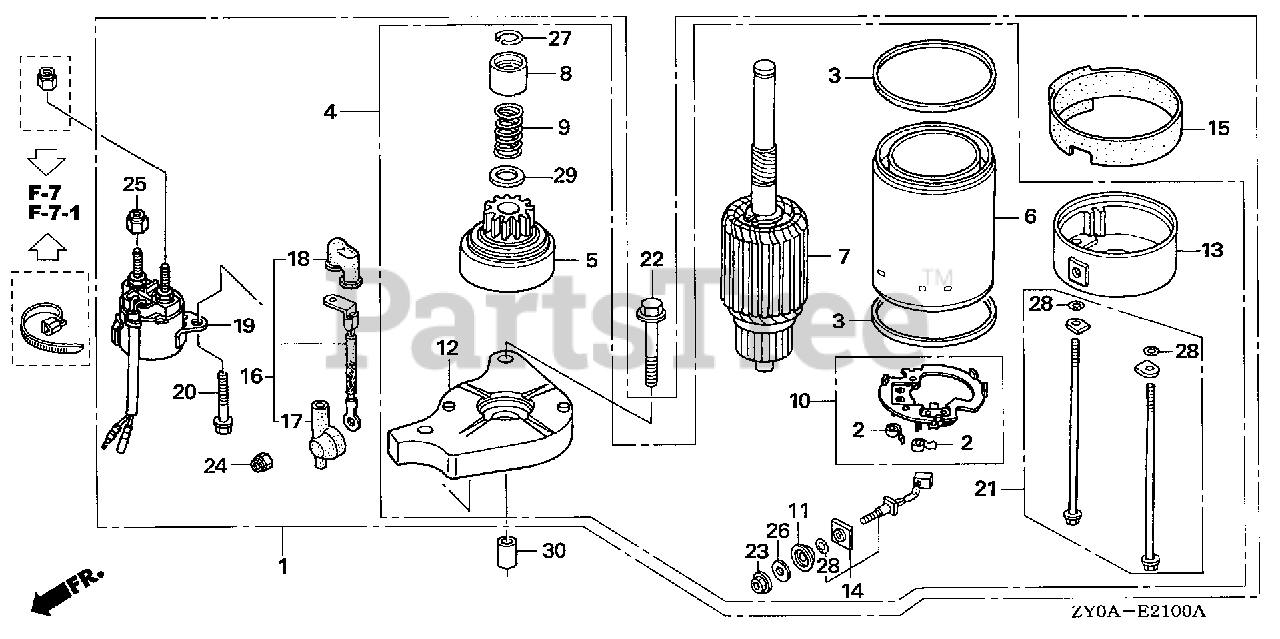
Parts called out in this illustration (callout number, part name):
1	STARTER MOTOR ASSY.
2	SPRING, CARBON BRUSH
4	STARTER MOTOR UNIT
8	PIECE, STOPPER
9	SPRING, RETURN
10	HOLDER, BRUSH
12	BRACKET, FR.
13	BRACKET, RR.
14	TERMINAL UNIT
15	SUSPENSION, STARTER
16	WIRE, MAGNETIC SWITCH
17	COVER, STARTER TERMINAL
18	COVER, MAGNETIC SWITCH TERMINAL
19	SWITCH ASSY., STARTER MAGNETIC
20	BOLT, FLANGE (6X14)
21	BOLT SET, SETTING
22	BOLT, FLANGE (8X45)
23	NUT-WASHER (6MM)
24	NUT, LOCK (6MM)
25	NUT, LOCK (6MM)
26	WASHER (6MM)
27	CIRCLIP (14MM)
28	O-RING (4X2)
30	PIN, DOWEL (10X12)
